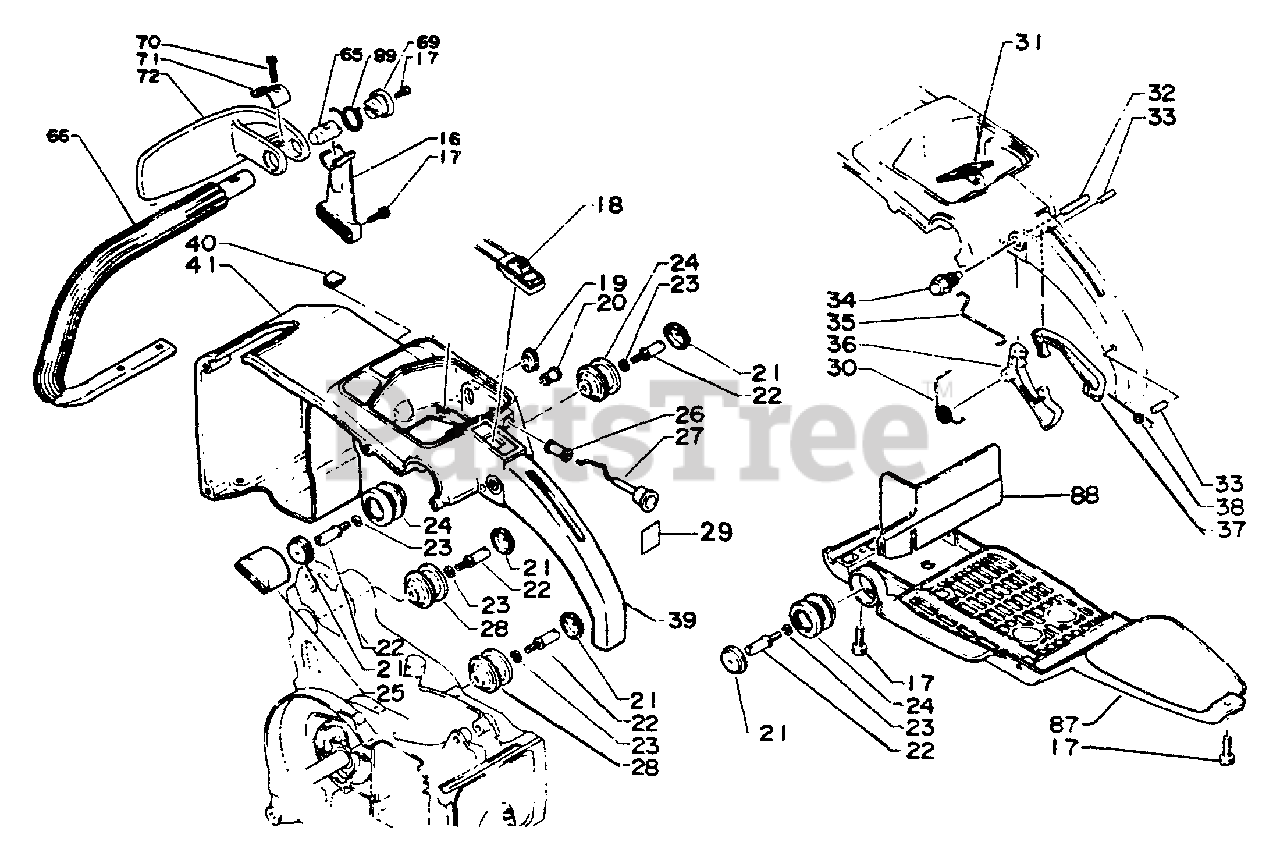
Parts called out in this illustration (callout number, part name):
16	BRACKET, HANDLE - UPPER
17	SCREW - 5X20
18	IGNITION SWITCH ASSY
20	GROMMET
21	CAP, CUSHION
23	LOCKWASHER - 5
25	COVER, CUSHION
26	GROMMET
27	ROD, CHOKE
29	LABEL - CHOKE
30	SPRING, TRIGGER
32	PIN - SPRING -- 5X25
33	PIN - SPRING -- 4X13
34	LATCH, THROTTLE
35	ROD, THROTTLE
36	TRIGGER, THROTTLE
37	LOCKOUT, THROTTLE
38	SPRING, LOCKOUT LEVER
39	GRIP, HANDLE - REAR
41	HANDLE - REAR
66	HANDLE - FRONT
69	PLATE, HAND GUARD
70	SCREW - 5X30
71	STOPPER
72	GUARD
73	COVER
87	Supporter, bottom
88	INSULATOR
